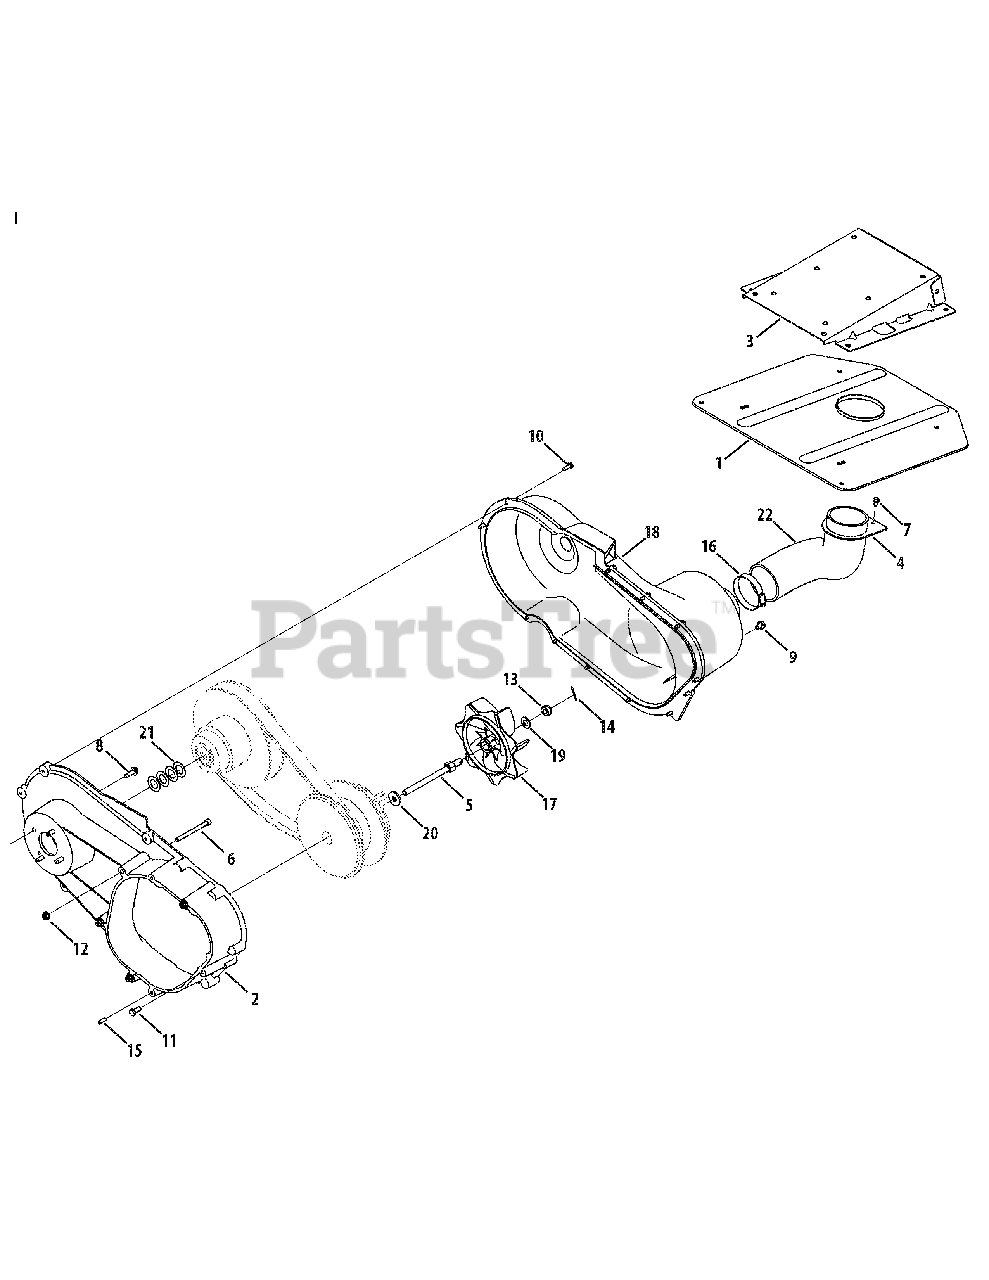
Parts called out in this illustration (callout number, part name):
2	Housing Assembly, CVT, CAT, 4x4
5	Hhcs, 7/16-20 x 5.00
6	Screw, 5/16-18 x 3.50
7	Screw, TT, 1/4-20 x .500
8	Screw, TT, 5/16-18 x 1.00
9	Screw, 5/16-12 x .500
10	Screw, TT, 1/4-20 x .750
11	Hhcs, 5/16-18 x .75
12	Nut, Flglk., 5/16-18
13	Nut, Hex, 1/2-20
14	Pin, Cotter, 3/32 x 1.00
15	Pin, Roll, .25 x .75
16	Clamp, Hose, Adj.
17	Impeller, Blower
18	Cover, CVT, 4x4
19	Washer, Flat, .510 x 1.00 x .060
20	Washer, Flat, .450 x 1.250 x .164
21	Washer, Flat, .793 x 1.368 x .025
22	Tube, Intake, CVT
